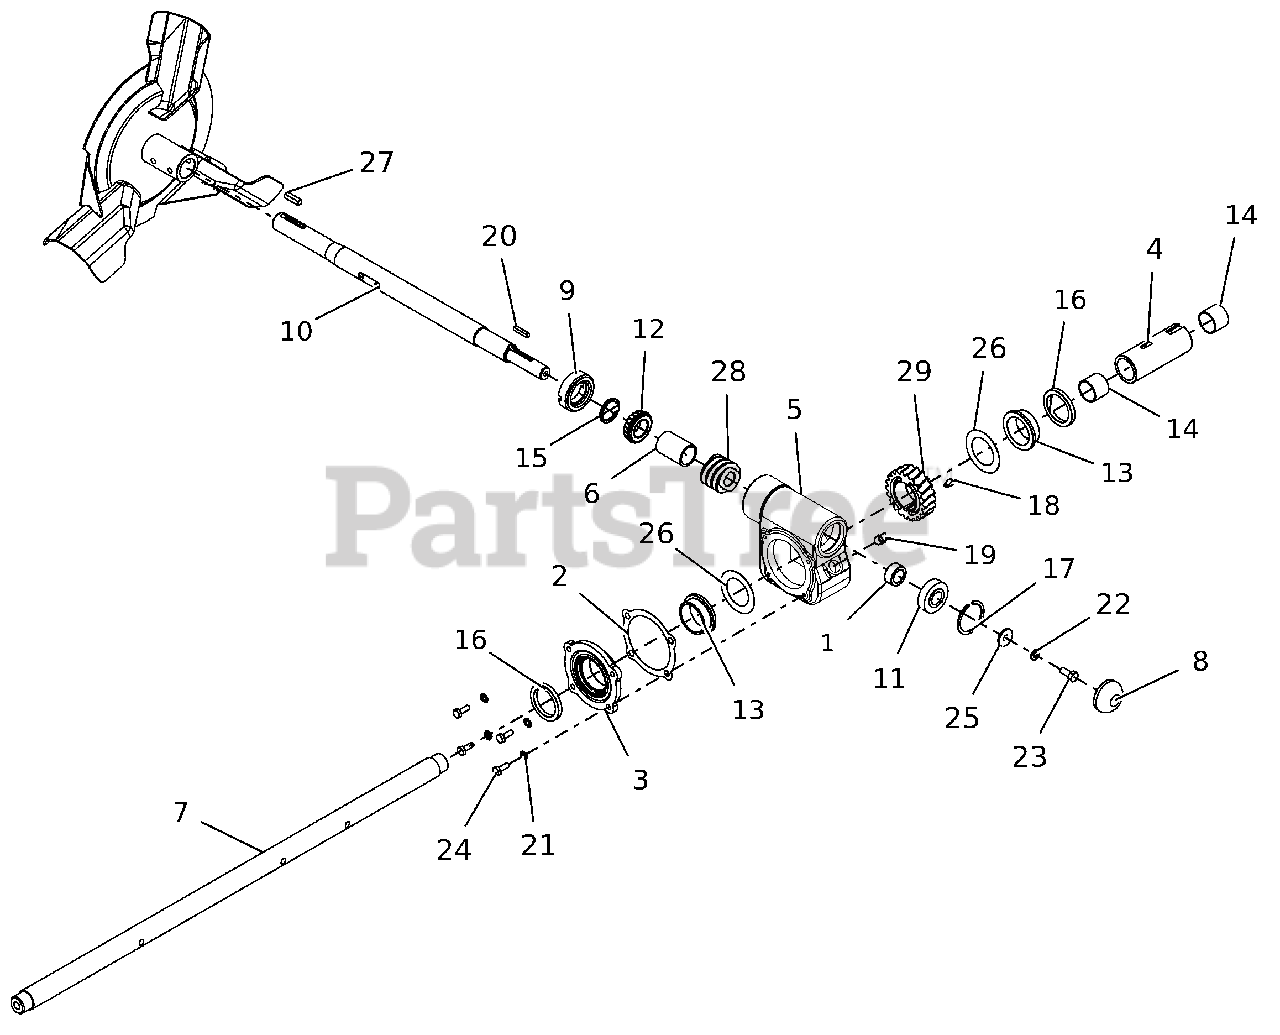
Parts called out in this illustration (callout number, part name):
1	BSHG, SPCR .755X1.12X.50 PM
3	COVER, GEAR CASE (BLACK)
4	GEAR CASE SHAFT
5	GEAR CASE
6	BEARING SPACER 1.032X1.25X1.78
7	32 INCH RAKE SHAFT
8	CAP,DUST,GEARBOX
9	PLUG,ADJUSTMENT
10	WORM SHAFT 16
11	BRG-CONE .750X.61
12	BRG-CONE 1.0X.58
13	BSHG-FLG .683X1.87X1.68X2.250
14	BSHG-SLV 1.125X1.250X1.000
15	SEAL 1.125X1.375X.125
16	SEAL 1.625X2.125X.250
17	RG-RTNG-INT 1.781X.062
18	KEY-FTHR .25X.875X.25 SAE 8630
19	PIPE PLUG, 1/4 NPT ZC120
20	KEY-SQ .188X1.0X.188 SAE 8630
21	WSHR,LK-EXT.262X.502X.026 ZCC
22	WSHR,LK-REG .312X.078 ZCC
23	BLT,HEX .31-18X.75 G5 ZCC
24	BLT, HEX .25-20X.75 G5 ZCC
25	WSHR,FLT .328X1.00X.094 ZCC
26	WSHR-FL-STL 1.625X2.500X.012
27	KEY, SQ .25X.25X1.00 RC 40-50
28	WORM, GEAR
29	WORM GEAR
